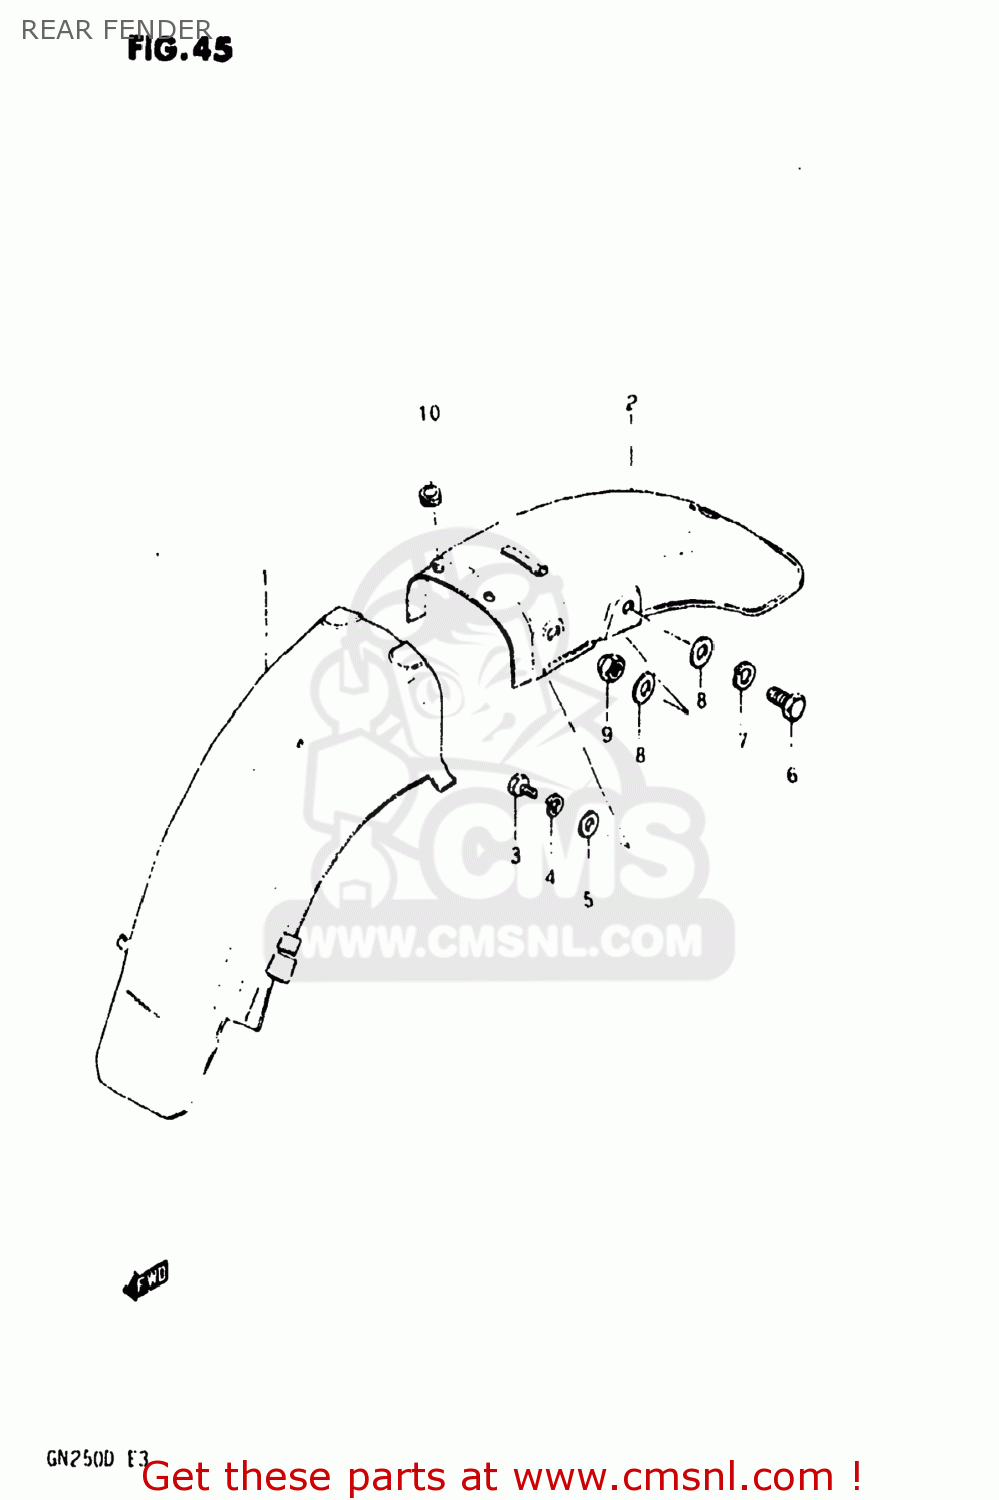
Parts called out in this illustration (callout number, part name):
1	FENDER,REAR
2	FENDER,REAR
3	BOLT
4	LOCK WASHER
5	WASHER
6	BOLT
7	LOCK WASHER
8	WASHER
9	NUT
10	CUSHION
